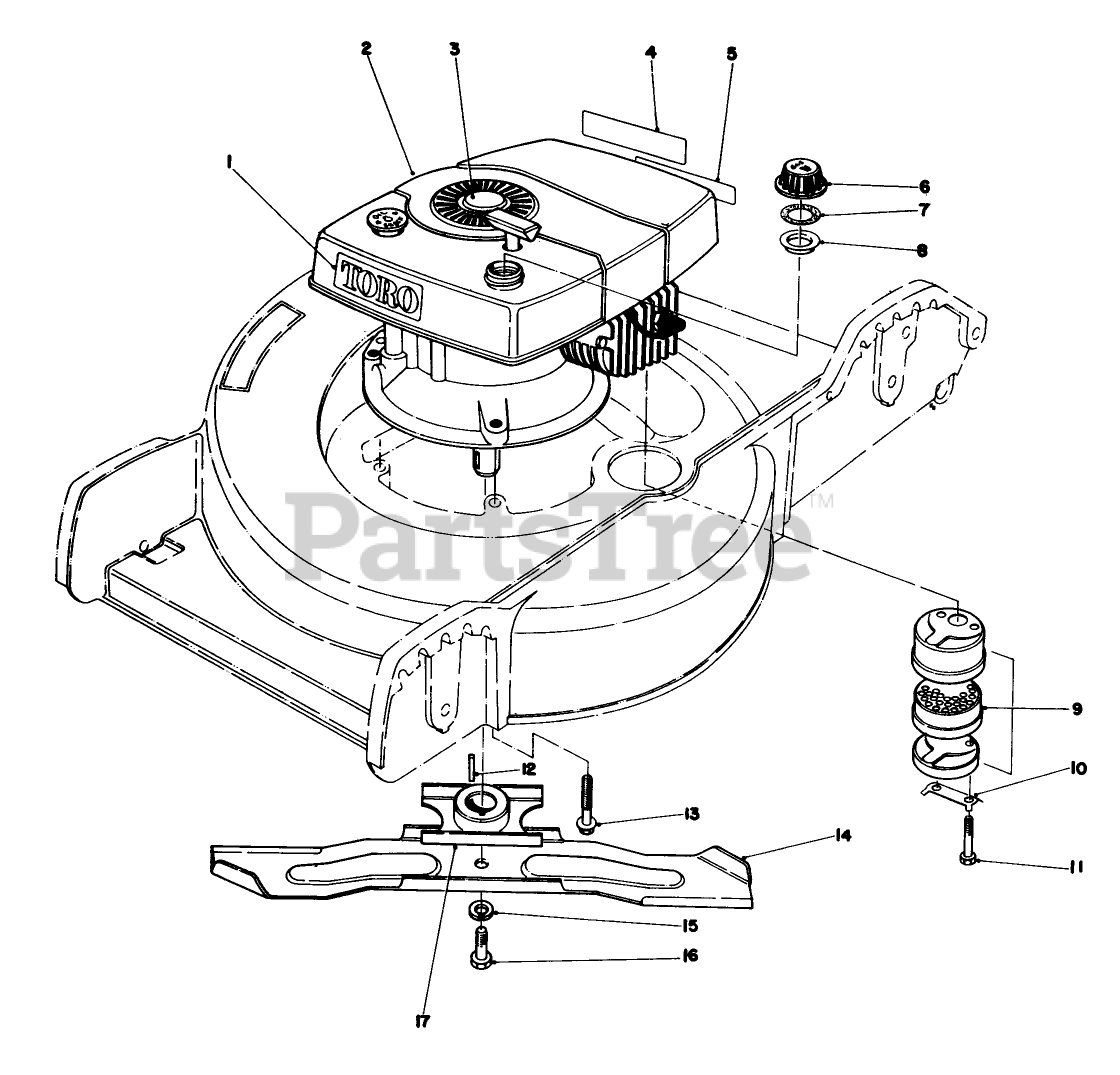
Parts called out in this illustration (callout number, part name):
1	Decal Toro
2	Engine
3	Plug Button
4	Decal Maintenance
5	Decal-Primer Bulb
6	Gas Cap (Incl. Ref. #7 & 8)
7	GASKET
8	GAS CAP BAFFLE
9	Muffler Assy. (Incl. Ref. #10 & 11)
10	CLIP - LOCKING
11	SCREW-HH
12	KEY-SQUARE
13	3/8-16 X 2 CAPSCREW
14	Blade
15	WASHER-LOCK
16	SPECIAL SCREW
17	Blade Retailer
